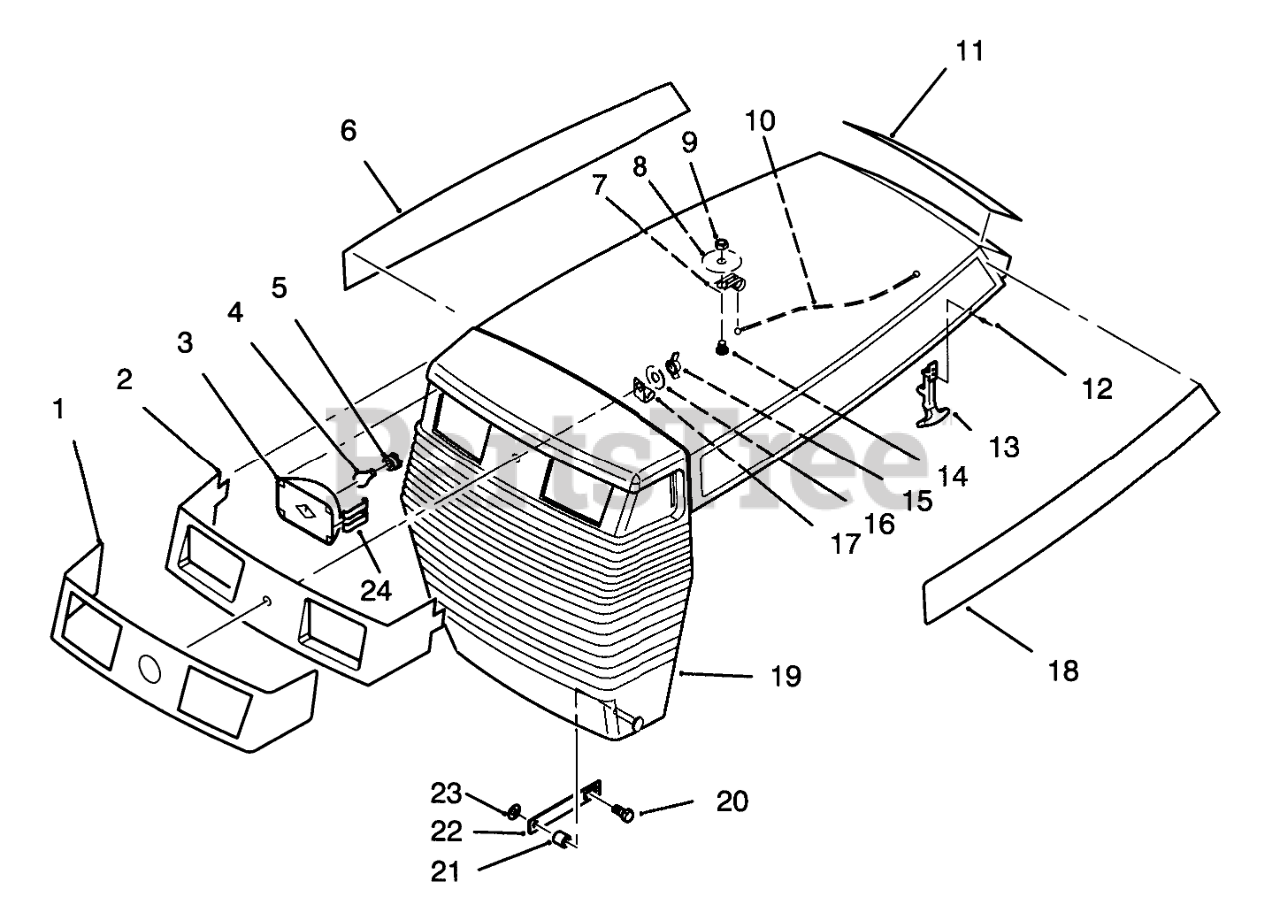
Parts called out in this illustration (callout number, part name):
1	DECAL-FRONT HOOD
2	LIGHT-BAR BLACK
3	LIGHT POD
4	BULB
5	SOCKET-HEADLIGHT
6	DECAL-HOOD 244-H R H
7	CLEVIS
8	WASHER-BACKING
9	Nut
10	CABLE-ASS'Y
11	DECAL - DANGER
12	RIVET-POP
13	HANDLE ASM
14	SCREW
15	WING NUT
16	WASHER
17	J-CLIP
18	DECAL-HOOD 244-H L H
19	Hood (Incl. Ref. #11)
20	Screw
21	SPACER
22	STRAP R
23	PUSH-NUT 5/16
24	RETAINER
